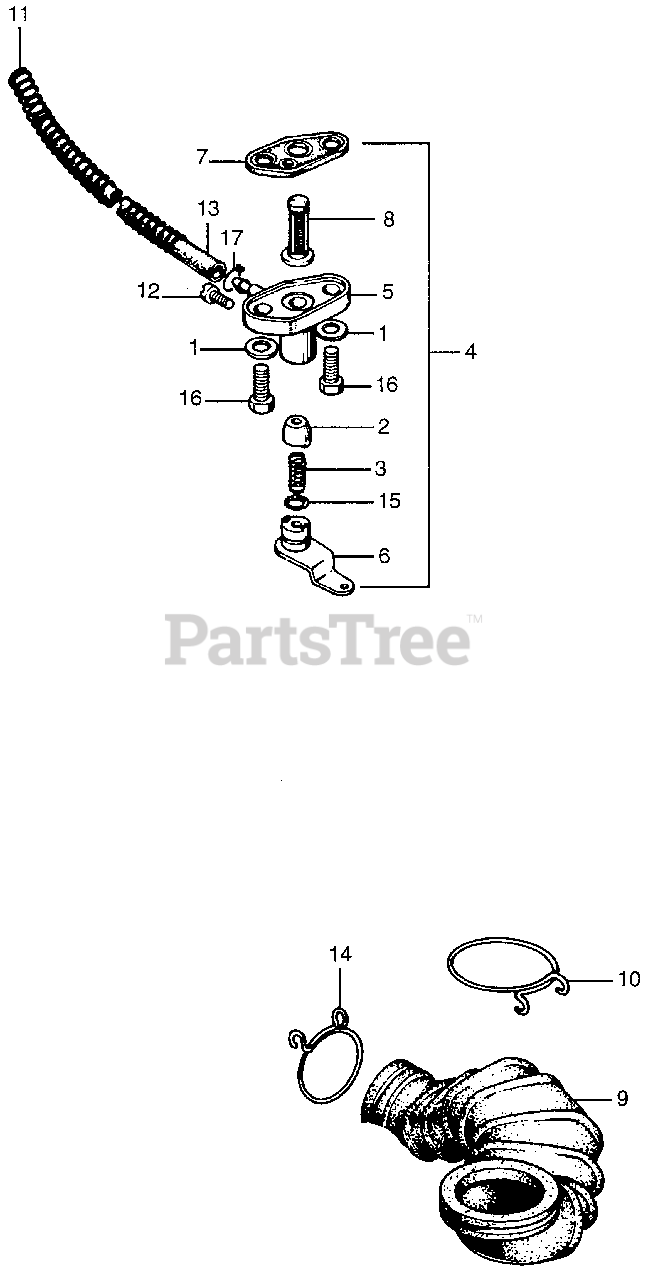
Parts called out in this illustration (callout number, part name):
1	GASKET, STRAINER SETTING (NOT AVAILABLE)
2	BODY, PETCOCK (NA USE ALT:16950-836-703)
3	SPRING, VALVE (NOT AVAILABLE)
4	LEVER ASSY., FUEL (NOT AVAILABLE)
5	BODY, LEVER
6	SHAFT, LEVER
7	GASKET A, PETCOCK (NOT AVAILABLE)
8	FILTER, CHECK (NOT AVAILABLE)
9	TUBE, CONNECTING (NOT AVAILABLE)
10	CIRCLIP (42MM) (NOT AVAILABLE)
11	SPRING, FUEL TUBE
12	SCREW, STOP
13	TUBE, FUEL
14	CIRCLIP (34MM)
15	O-RING (9X1.3) (NOT AVAILABLE)
16	BOLT, HEX. (6X20)
17	CLIP, TUBE (B8)
17	CLIP, TUBE (4.5)
